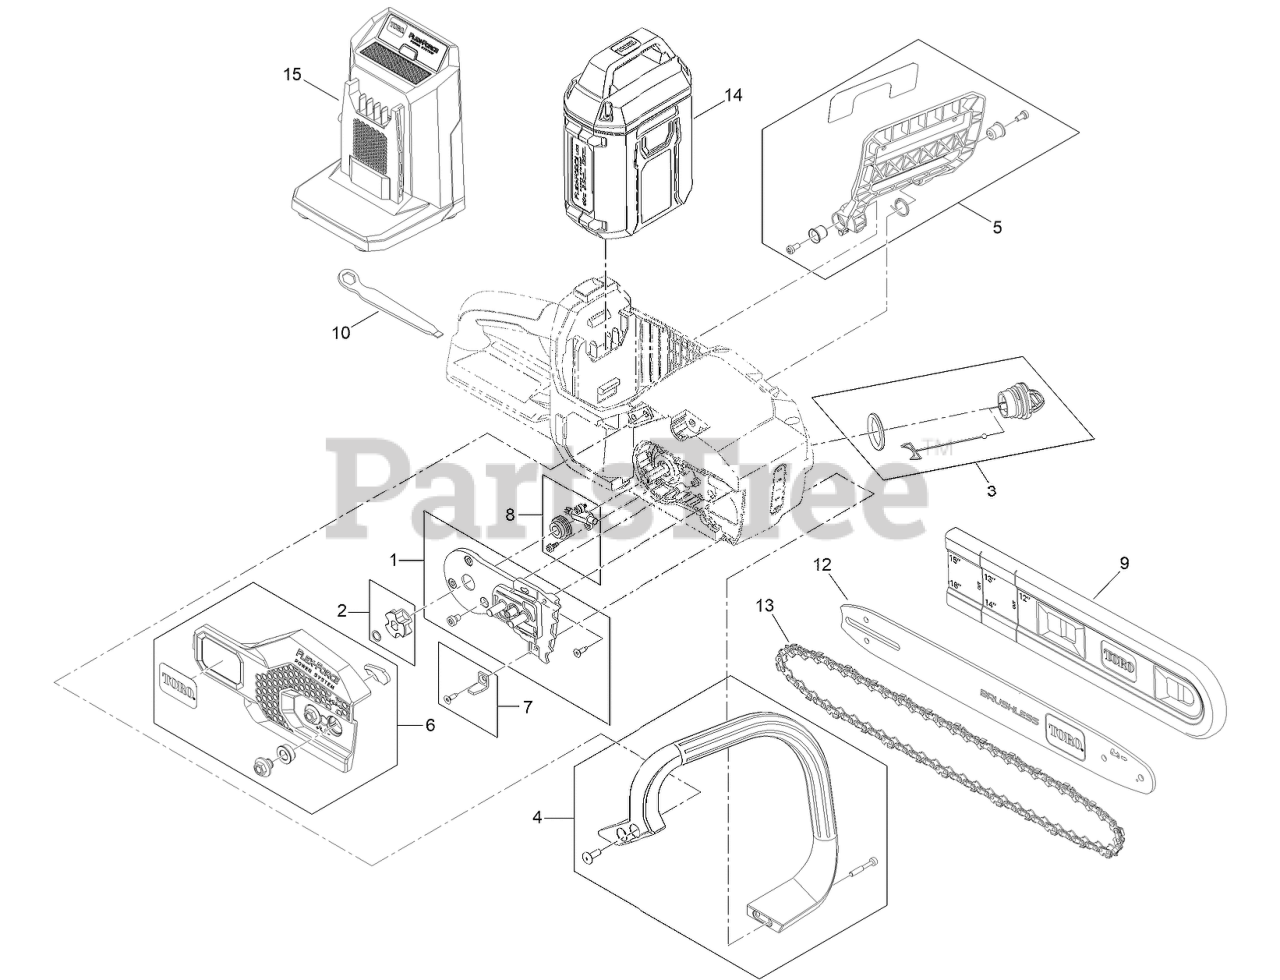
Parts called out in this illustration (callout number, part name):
1	ADJUSTER BAR BRACKET ASM
2	DRIVE GEAR ASM
3	OIL CAP ASM
4	HANDLE ASM
5	CHAIN BRAKE ASM
6	BAR COVER ASM
7	BAR COVER SUPPORT BRACKET ASM
8	OIL PUMP ASM
9	BAR-SLEEVE, CHAINSAW
10	TOOL-ADJUSTMENT, BAR
12	BAR-REPLACEMENT
13	CHAIN
14	BATTERY-LI ION, 60V 2.5 AH
15	CHARGER-BATTERY, 60V 2 AMP
